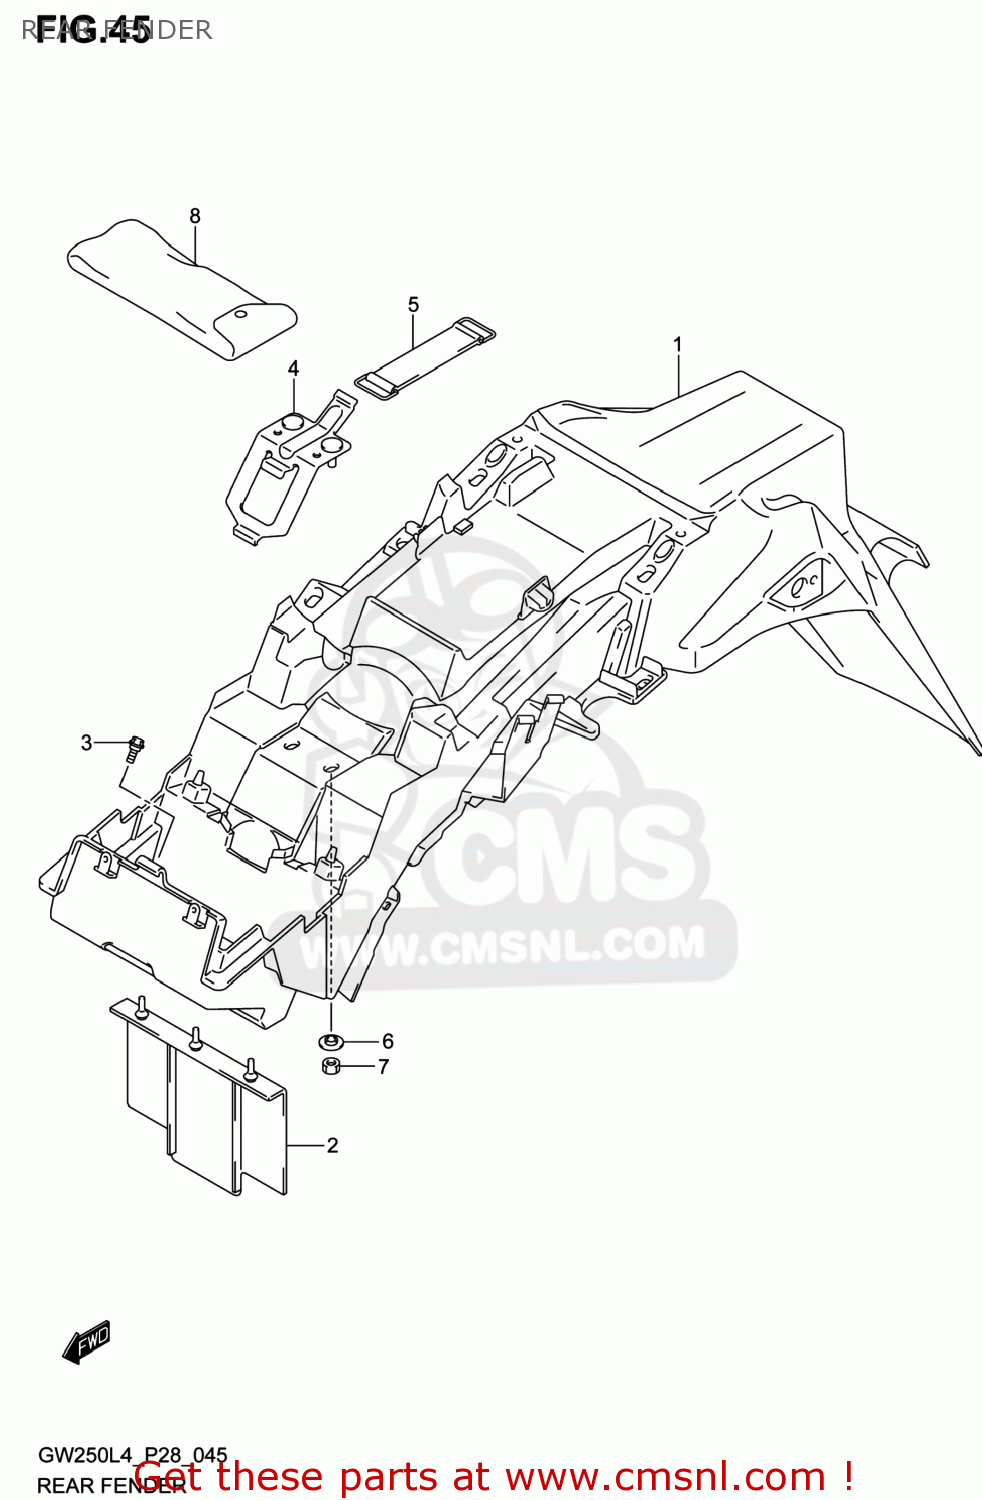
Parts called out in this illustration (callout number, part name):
1	FENDER,REAR
2	MUDGUARD,RR FENDER
3	BOLT(6X12)
4	HOLDER,TOOL
5	BAND,TOOL
6	WASHER,TOOL HOLDER
7	NUT
8	TOOL ASSY
